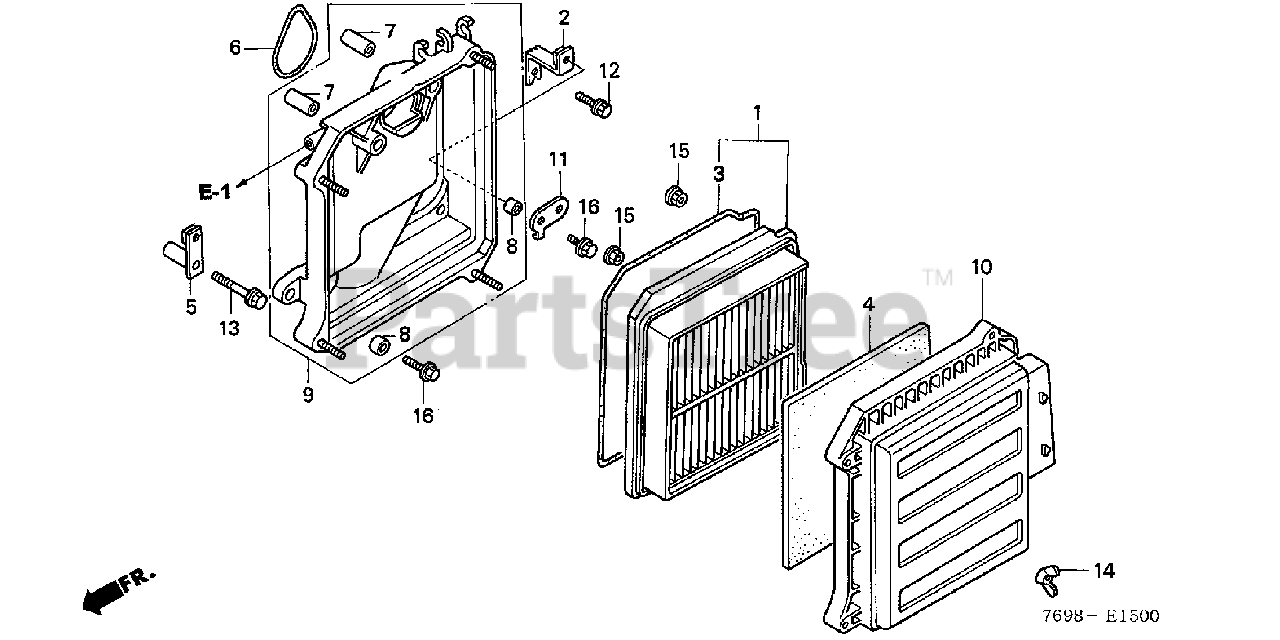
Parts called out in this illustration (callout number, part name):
1	ELEMENT KIT, AIR CLEANER
2	BRACKET, R. AIR CLEANER
3	GASKET, ELEMENT
4	FILTER (OUTER)
5	BRACKET, L. AIR CLEANER
6	GASKET, AIR CLEANER
7	COLLAR, AIR CLEANER
8	COLLAR B, AIR CLEANER
9	CASE, MUFFLER
10	COVER, MUFFLER
11	STAY, WIRE CLIP (B)
12	BOLT, FLANGE (6X14)
13	BOLT, FLANGE (6X45)
14	NUT, TOOL BOX SETTING
15	NUT, FLANGE (6MM)
16	BOLT, FLANGE (6X20)
